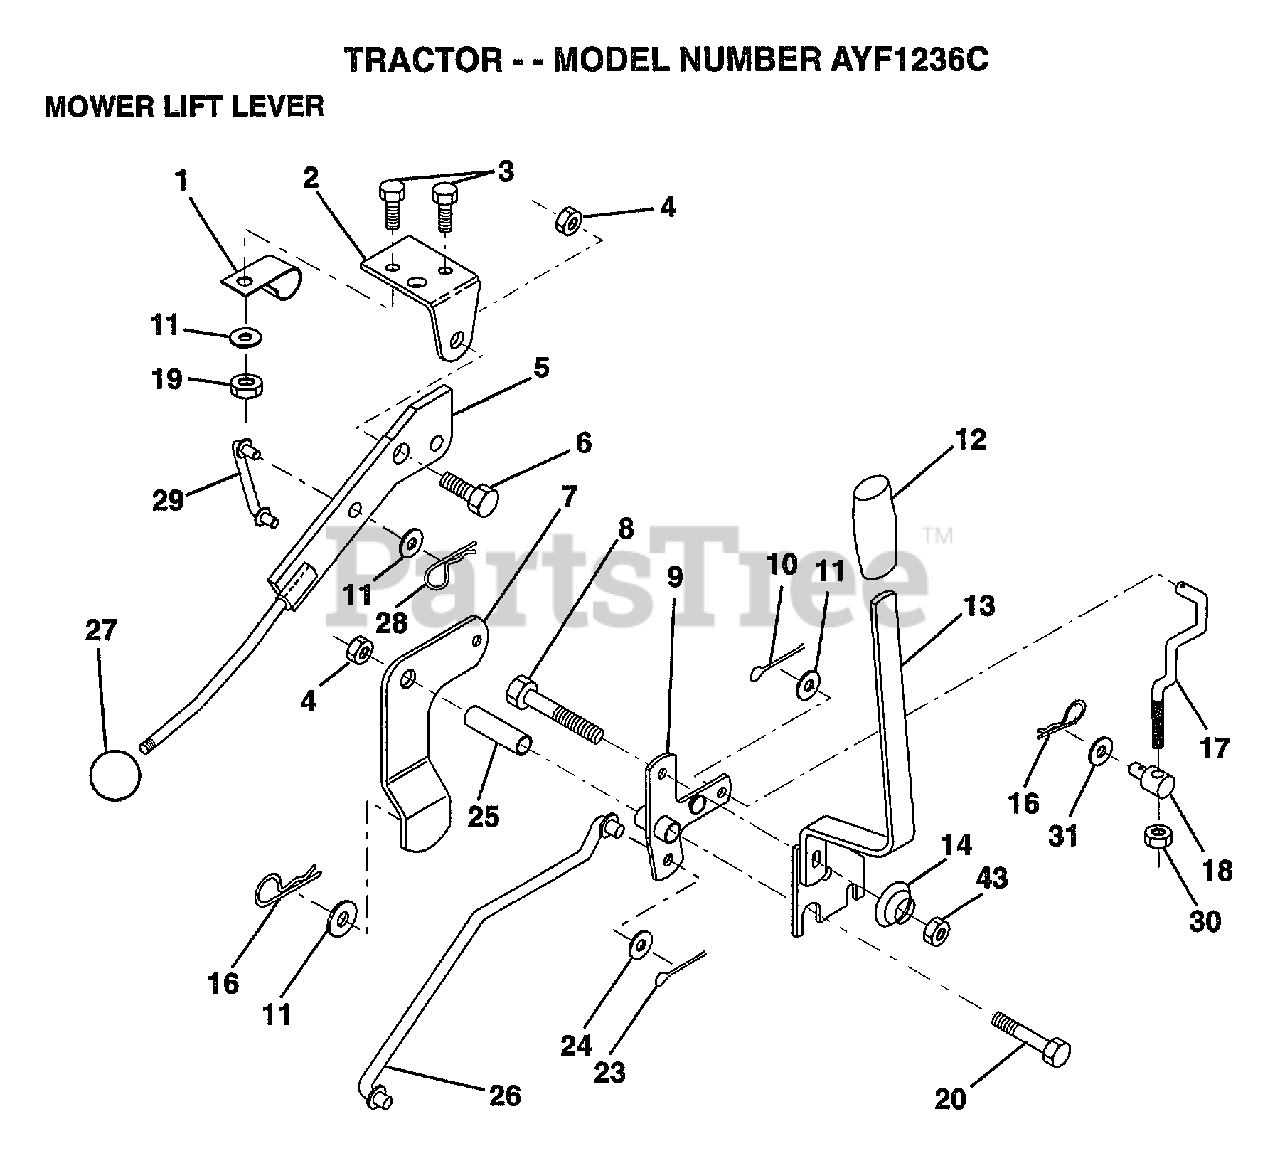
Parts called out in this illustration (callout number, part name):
1	"CLIP,INSULATOR"
2	BRKT CLUTCH
3	BOLT HXHD FIN
5	LEVER.ASM.CLUTCH
6	"BOLT, SHOULDER LT"
7	MWR CLUTCH ARM AS
8	BOLT
9	"BELLCRANK,LIFT"
10	COTTER PIN
11	WASHER
13	HANDLE.ASM.LIFT
14	SPRING COMPRESSIO
16	SPRING.RETAINER
17	"LINK,LIFT FRT"
18	TRUNION ADJ
19	NUT HXKEP 1/4X20
20	BOLT
23	PIN COTTER 1/8
25	TUBE SPACER
26	ROD LIFT MOWER
27	KNOB T(3/8 HOLE)
28	RETAINER M
29	CLUTCH LINK
30	NUT
31	WASHER
